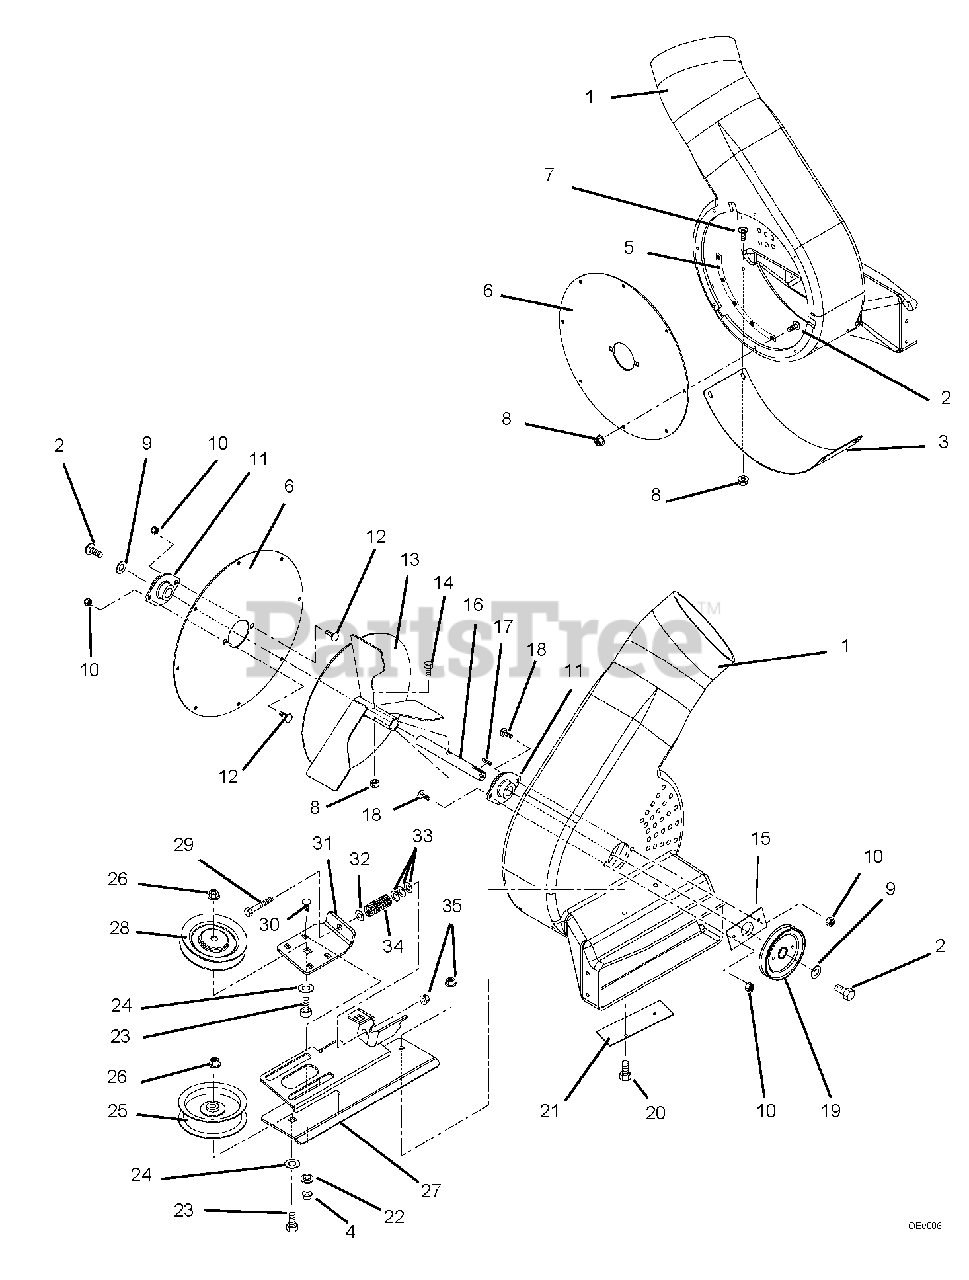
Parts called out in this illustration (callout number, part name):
1	Housing, Blower
2	Screw, Machine .25-20 x .50
3	Plate, Skid
4	Nut, Locking-Top-Flange .25-20
5	Plate, Mounting Bolt Reinforcing
6	Plate, Bearing Mount
7	Screw, Machine .25-20 x .75
8	Nut, .25-20 Nyloc Flange
9	Washer, Flat-Steel .344 x 1.125 x .135
10	Nut, Locking-Nylon .312-18
11	Bearing, 2 Bolt Flange - .75 ID
12	Bolt, Round Head Square Neck .31-18X.62
13	Weldment, Impeller, 3 Blade
14	Bolt, Hex .25-20 x 1.50 Grade 5
15	Plate, Washer Bearing
16	Shaft, Impeller
17	Key, Square .187 x .50 x .187 Hardened
18	Bolt, Round Head Square Neck .31-18 x .88 Grade 5
19	Sheave, Blower- 4.25 Diameter
20	Bolt, Hex .31-18 x .875 Grade 5
21	Plate, Back
22	Bushing, Flange .265 x .437 x .250 x .750
23	Bolt, Hex .38-16 x 1.75 Grade 5
24	Washer, Flat, Steel .406 x .812 x .065
25	Idler Flanged 3.50
26	Nut, Locking-Top-Flange .38-16
27	Weldment, Idler Mount
28	V-Idler, 4.00 x .38
29	Bolt, Hex .31-18 x 4.00 Grade 5
30	Bolt, Round Head Square Neck .25-20 x .75 Grade 5
31	Bracket, Adjustable Idler
32	Nut, Push .312
33	Washer, Flat-Steel .406 x 1.00 x .188
34	Spring, Compression .092 x .77 x 3.13
35	Nut, Locking-Top-Flange .31-18
36	Blower, Service Assembly (includes items 1-37)
